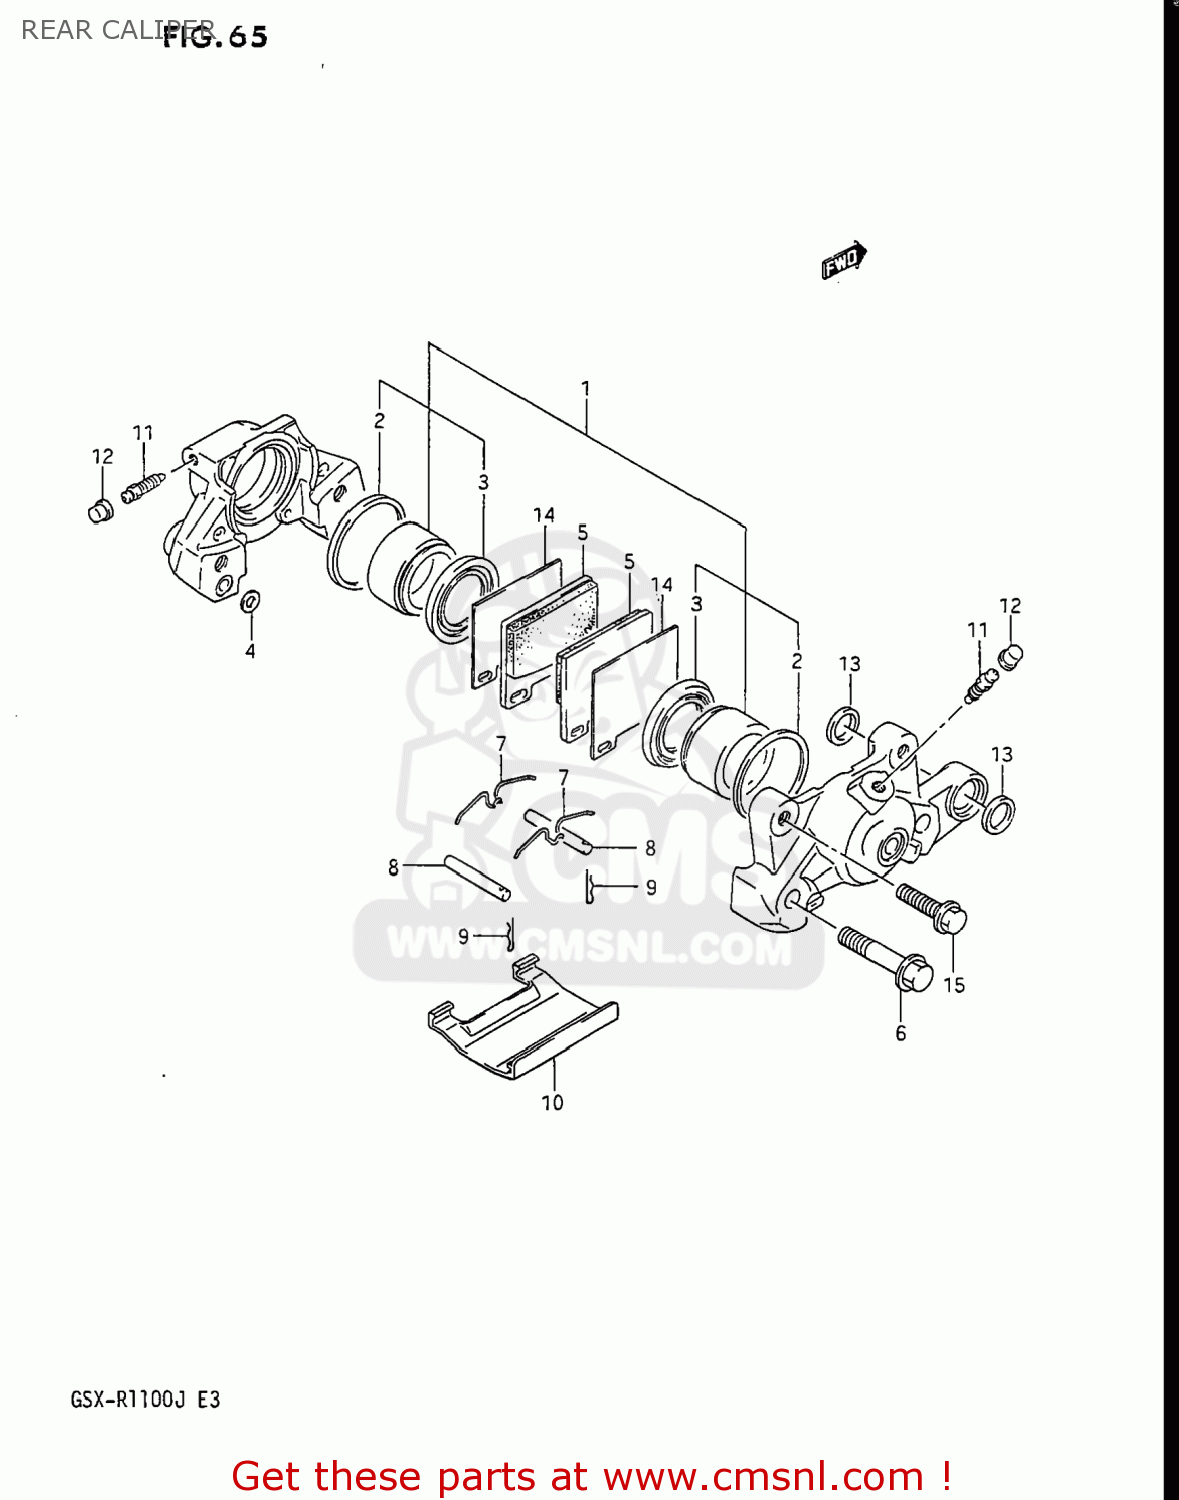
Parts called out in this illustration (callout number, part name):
1	PISTON SET
2	SEAL,PISTON
3	BOOT
4	SEAL,JOINT
5	PAD,BRAKE
6	BOLT,HOUSING
7	SPRING
8	PIN,PAD
9	CLIP,PAD PIN
10	COVER
11	BLEEDER
12	CAP,BREATHER
13	SEAL,RR CUSHION ROD LWR
14	SHIM,PAD
15	BOLT
